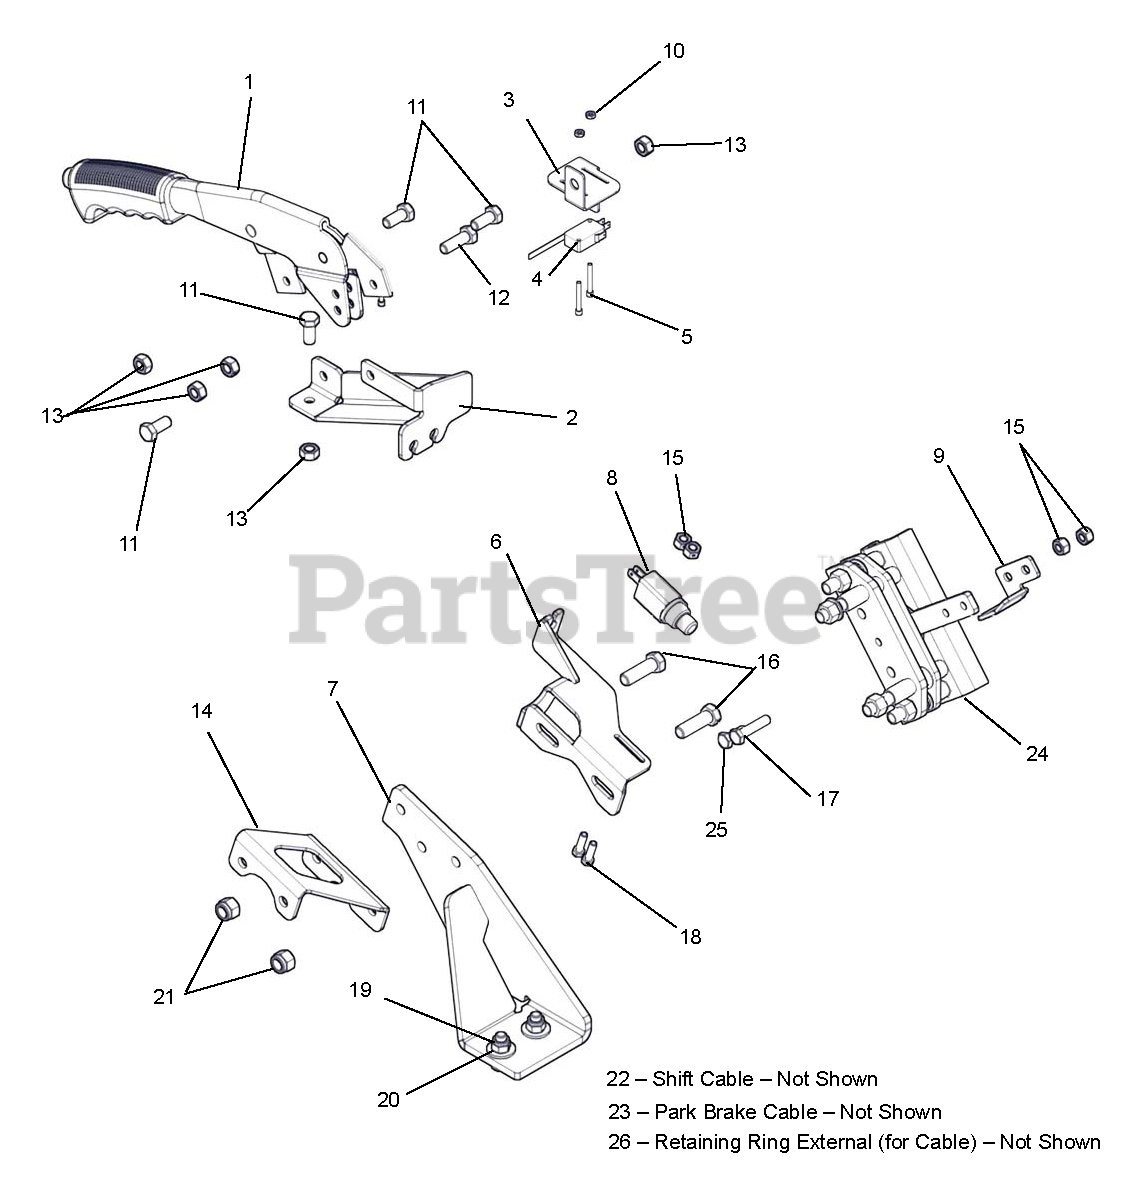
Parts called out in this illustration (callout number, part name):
1	PARK BRAKE LEVER
2	BRACKET,E-BRAKE MNT-BLK
3	BRACKET, PARK SWITCH
4	PARK BRAKE MICRO-SWITCH
5	HSHCS #4-40X1
6	CABLE MNT, PARK BRAKE
7	BRACKET, CALIPER MNT, BLCK
8	SWITCH-SINGLE POLE N.O.W/COVER
9	MOUNT,SWITCH,PARK BRAKE
10	NUT-HEX 4-40 YWZC GR5
11	@BLT-HEX .31-18X.75 GR5 YWZC
12	@BLT-HEX .31-18X1.00 GR5 YWZC
13	@NUT-LK-CTR .31-18 YWZC
14	BRACE, CALIPER MNT, P-BRAKE
15	@NUT-LK-CTR #10-24 YWZC
16	@BLT-HEX .38-16X1.25 GR5 YWZC
17	@BLT-HEX .25-20X1.25 GR5 YWZC
18	BLT-HEX 10-24X.75 PL GR2
19	@NUT-LK-NYL .312-18 YWZC
20	@WSHR-FL-STL.38X.875X.083 YWZC
21	@NUT-LK-NYL .38-16 YWZC
24	BRAKE CALIPER
25	@BLT-HEX .25-20X.75 GR5 YWZC
26	E RETAINING RING EXTERNAL
